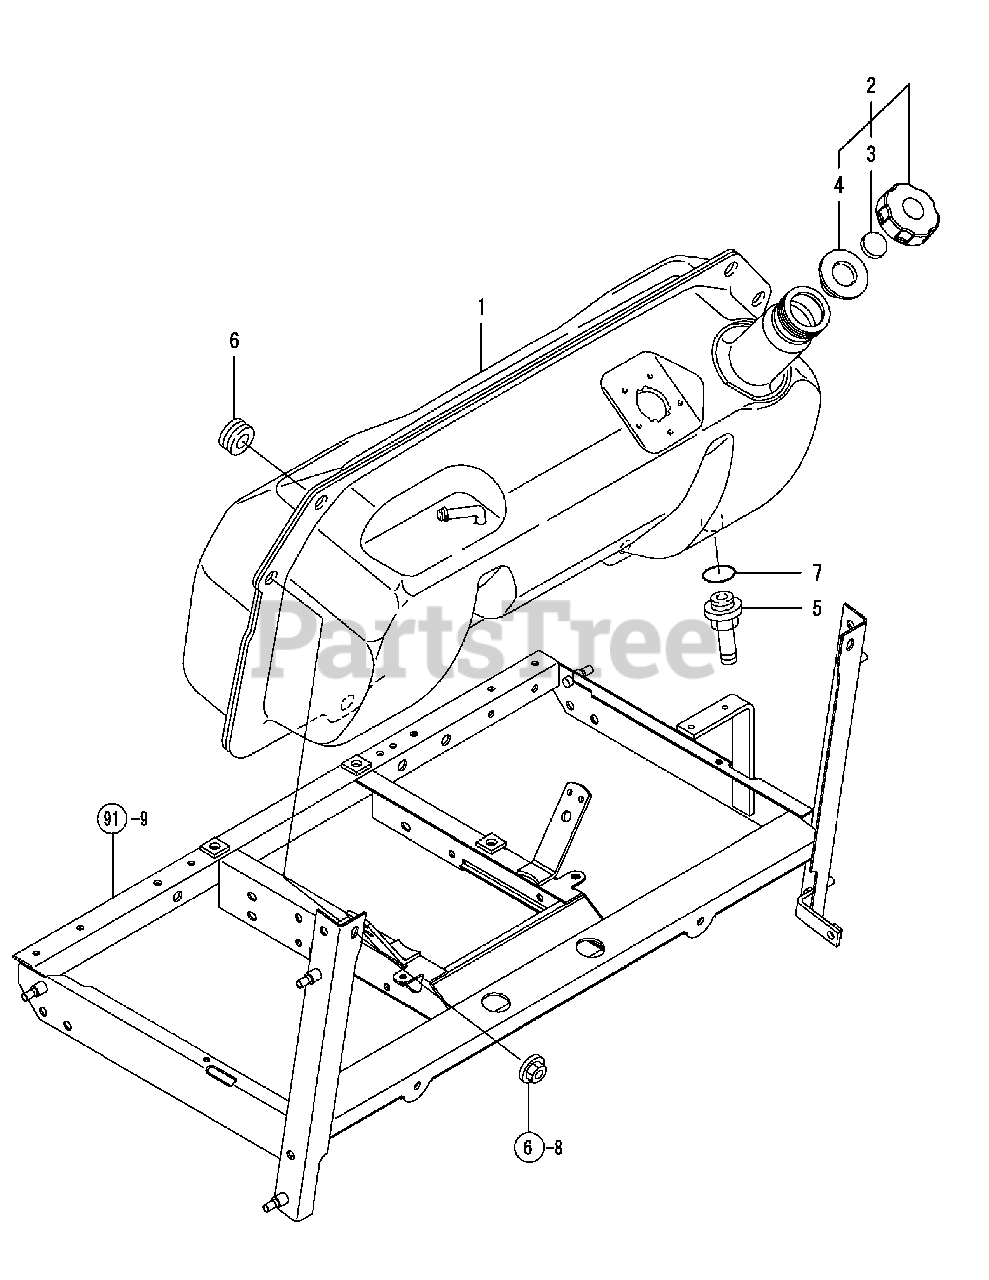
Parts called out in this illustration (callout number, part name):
1	TANK ASSY, FUEL OIL
2	CAP ASSY, FILLER
3	PACKING,FUEL CAP
6	GROMMET 25
7	O-RING 1A P-15.0
